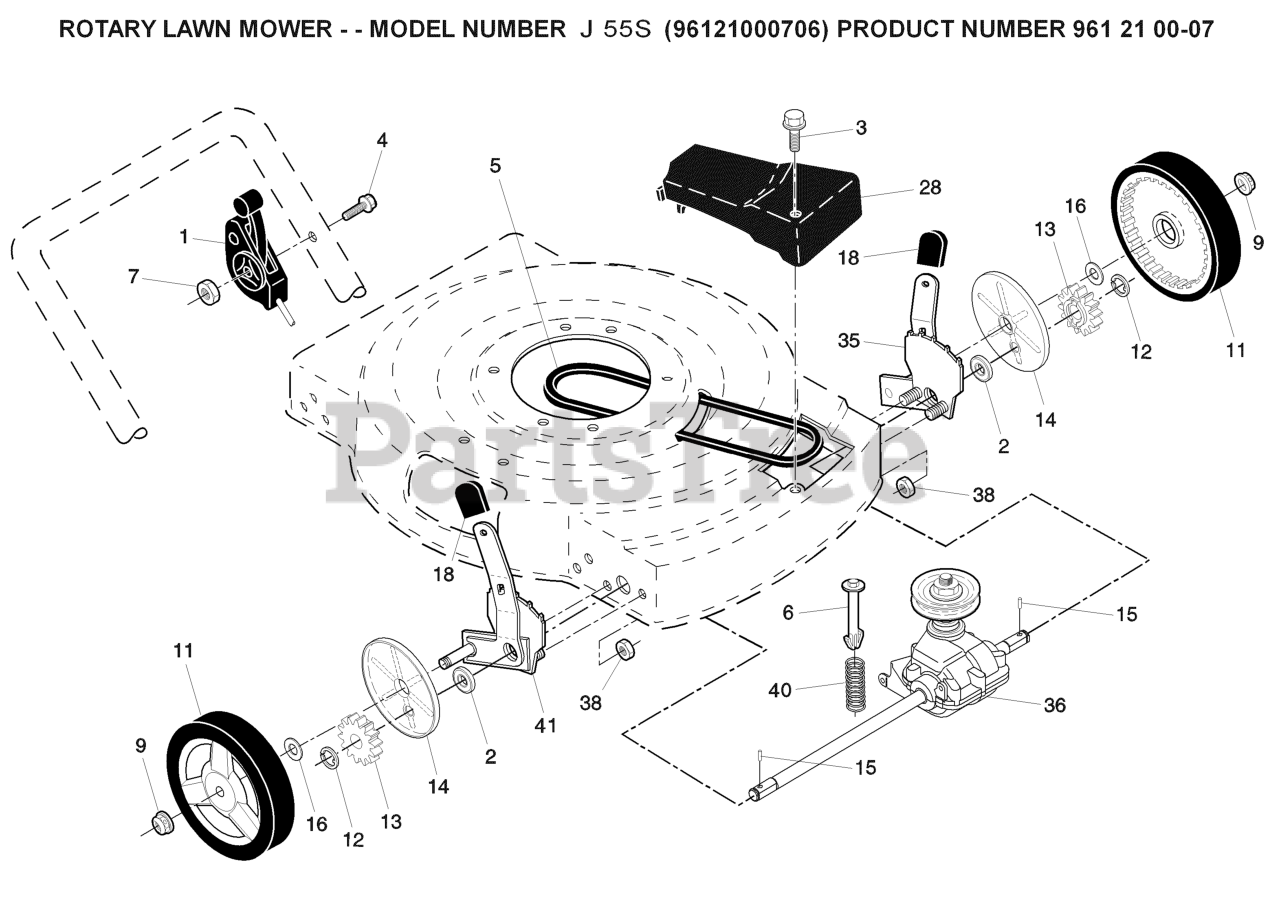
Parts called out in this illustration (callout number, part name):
1	DRIVE CONTROL 59.8 FWGD
2	BEARING
3	Screw, Tapping, Pan Head #10-24 x 2-3/4
4	SCREW.PAN.HEAD
5	BELT THERM .32
6	SPRING RETAINER
7	NUT.HEX.FLANGE.1/4
9	NUT.HEX.FLANGE.3/8-16.LO(3 2)
11	WHEEL.8X1.75.H3SPK.RAD3.GY.BU3
12	E-RING 7/16 RE
13	PINION.14.TEETH.FGD
14	COVER.DUST.WHEEL
15	PAWL, DRIVE
16	WASHER FLUT
18	SELECTOR KNOB
28	Drive Cover
35	WHEEL ADJ KIT LH
36	TRANSMISSION.22.FGD/W/PULLEY
38	LOCKNUT.NYLOC.1/4-20
40	SPRING.EXTENSION
41	WHEEL ADJ KIT RH
